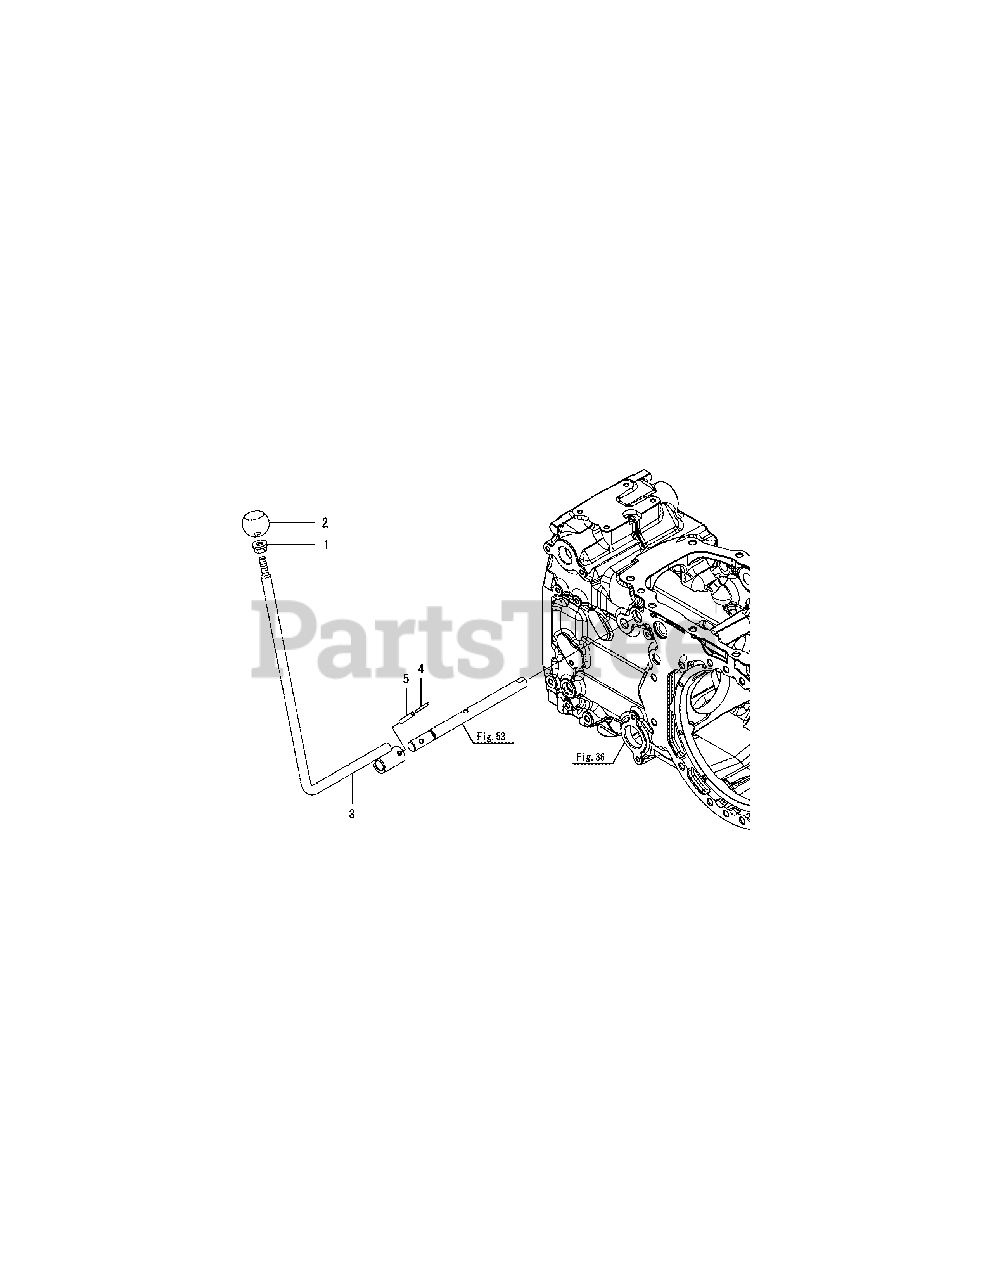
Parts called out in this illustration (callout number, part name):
1	NUT W/WASHER 10
3	LEVER ASSY, RANGE
4	SPRING PIN 3.5X40
5	SPRING PIN 6X40
